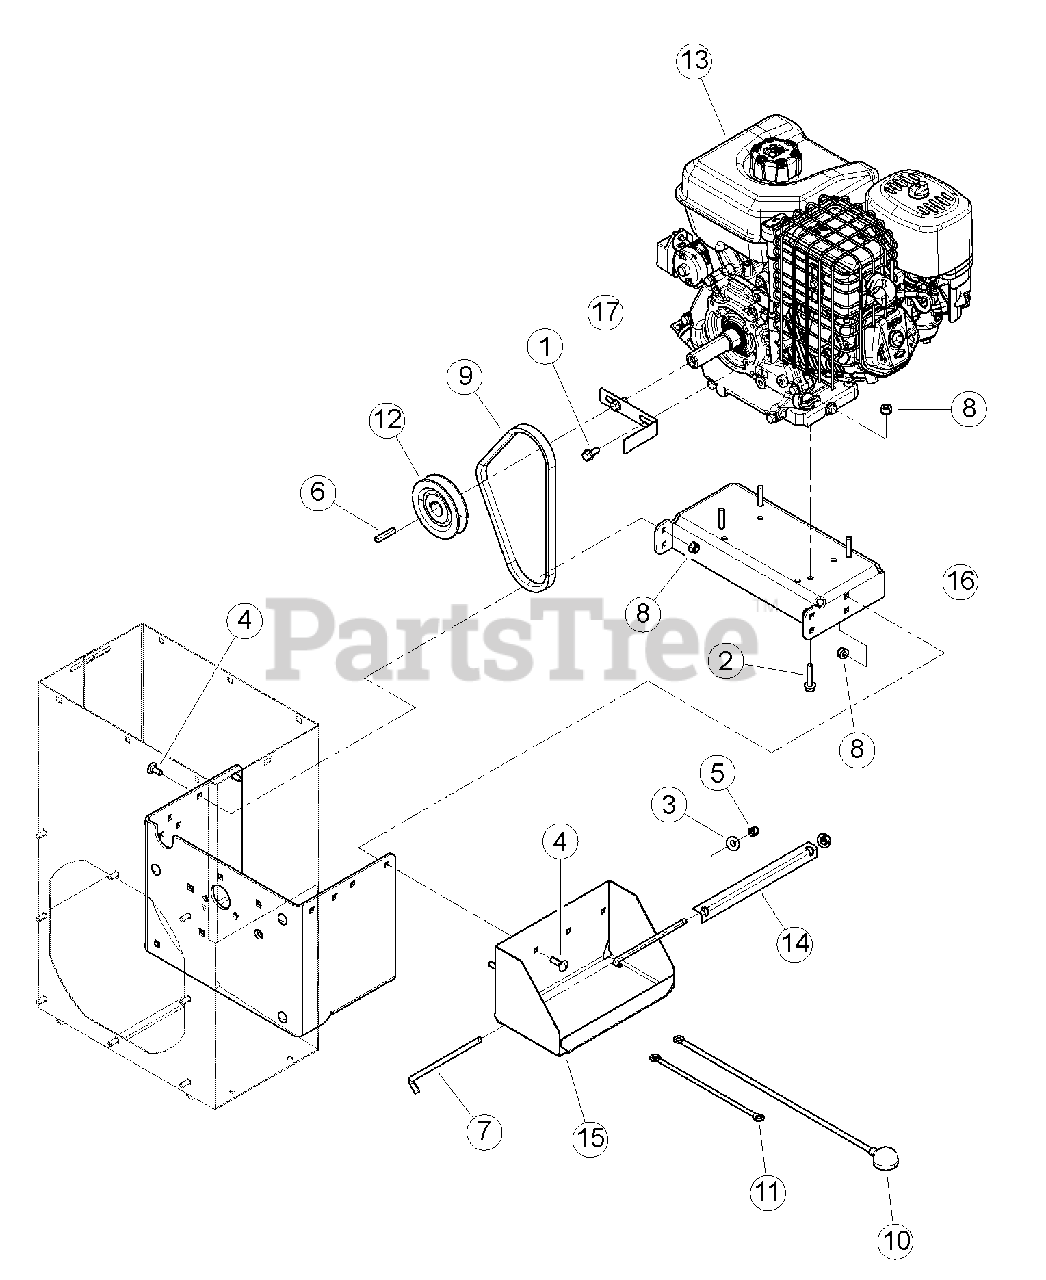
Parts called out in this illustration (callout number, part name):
1	BOLT, 5/16 X 3/4 SERRATED FLANGE NF
2	BOLT, 5/16 X 1-1/2 FLANGE NC
6	KEY, 1/4 SQUARE X 1-1/2 LONG PLAIN
8	NUT, 5/16-18 NYLOCK-FLANGE
9	BELT, 29" C/S
12	PULLEY, CAST 4" OD 1" BORE B GRV
13	ENGINE, 306CC B&S HORIZONTAL ELECTRIC
13	ENGINE, 306CC B&S HORIZONTAL
16	PLATE, ENGINE MOUNTING
17	GUIDE, BELT
